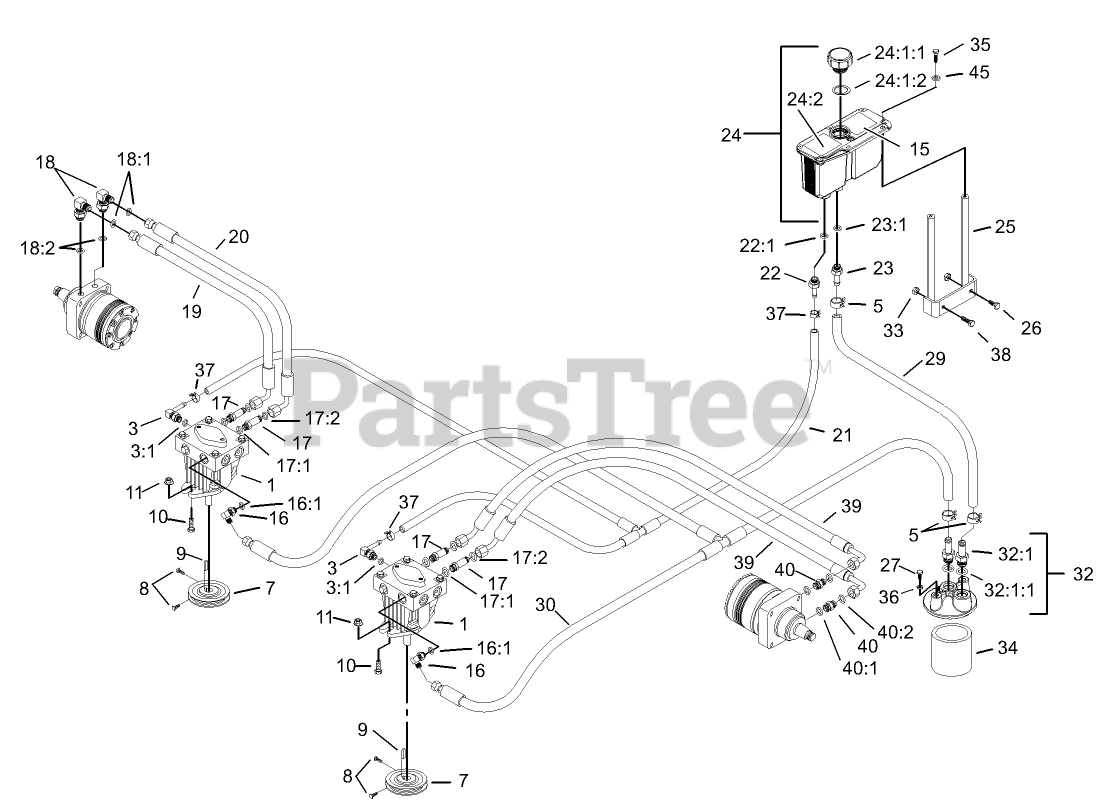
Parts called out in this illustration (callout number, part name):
1	PUMP-HYD
3	ELBOW-90 DEG
3:1	O-RING
5	Clamp-Hose
7	SHEAVE ASM
8	SCREW-SET
10	SCREW-HH
11	NUT-HHF, WHIZ
15	DECAL-EXHAUST
16	FITTING-ELBOW, 90 DEG
16:1	O-RING
17	ADAPTER-HYD, STRAIGHT
17:1	O-RING
17:2	O-Ring
18	FITTING-HYD, 90 DEG
18:1	O-Ring
18:2	O-RING
19	HOSE-FRONT
20	HOSE-REAR, RH
21	HYD HOSE ASM
22	Adapter-Straight
22:1	O-RING
23	ADAPTER-STRAIGHT
23:1	O-RING
24	HYD Reservoir ASM
24:1	Reservoir-HYD
24:1:1	CAP-RESERVOIR, HYD
24:1:2	GASKET-CAP
24:2	DECAL-TANK, HYD
25	STAND-RESERVOIR
26	SCREW-HH
27	SCREW-HH
29	HYD HOSE ASM
30	HYD HOSE ASM
32	Filter Head ASM
32:1	ADAPTER-STRAIGHT
32:1:1	O-RING
33	NUT-HF
34	FILTER-OIL, HYD
34	FILTER-OIL, HYD (WINTER)
35	SCREW-HH
36	WASHER-LOCK
37	Clamp-Hose
38	SCREW-HH
39	HOSE-LH
40	Fitting-Straight
40:1	O-RING
40:2	O-Ring
45	WASHER-FLAT
